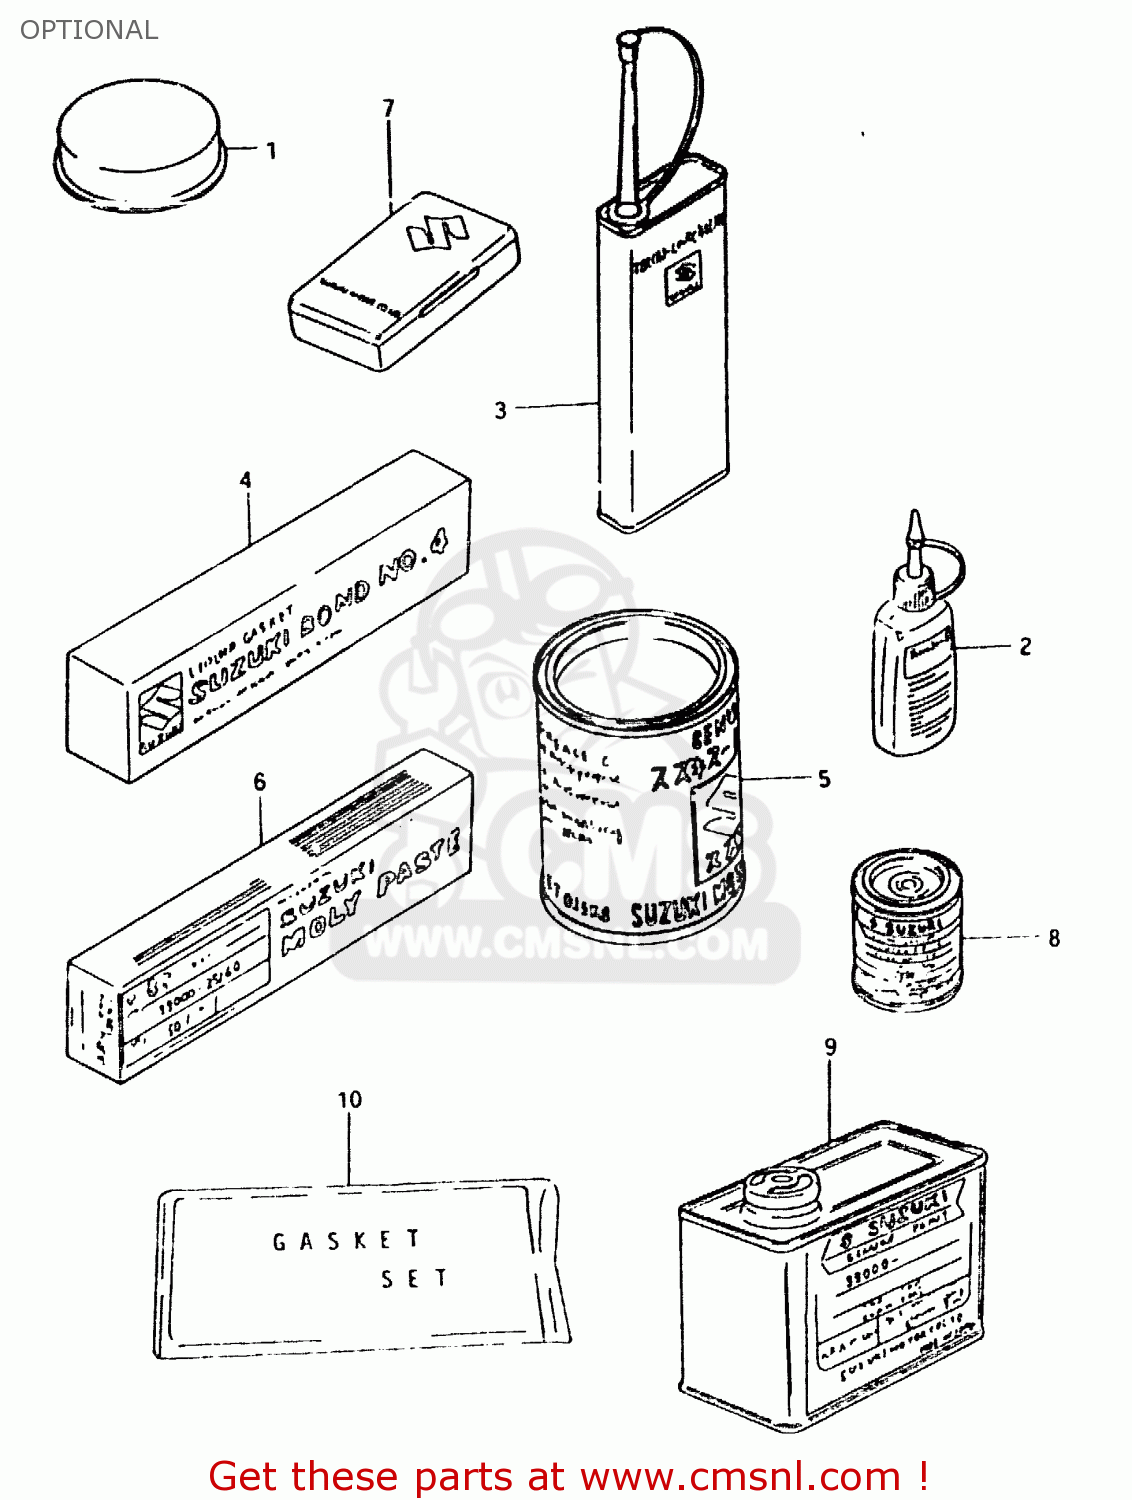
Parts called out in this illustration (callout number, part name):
1	GREASE,PBC FOR BRK PAD 20G
2	THREAD LOCK SUPER (1332B)
3	THREAD LOCK NO.1401 CLEAR 200G
4	BOND 1104
5	GREASE(C)EP2 LITHIUM 150G
6	SUZUKI MOLY PASTE
7	TUBE REPARING TOOL
8	PAINT,BLACK
9	PAINT (BLACK)
10	GASKET SET
